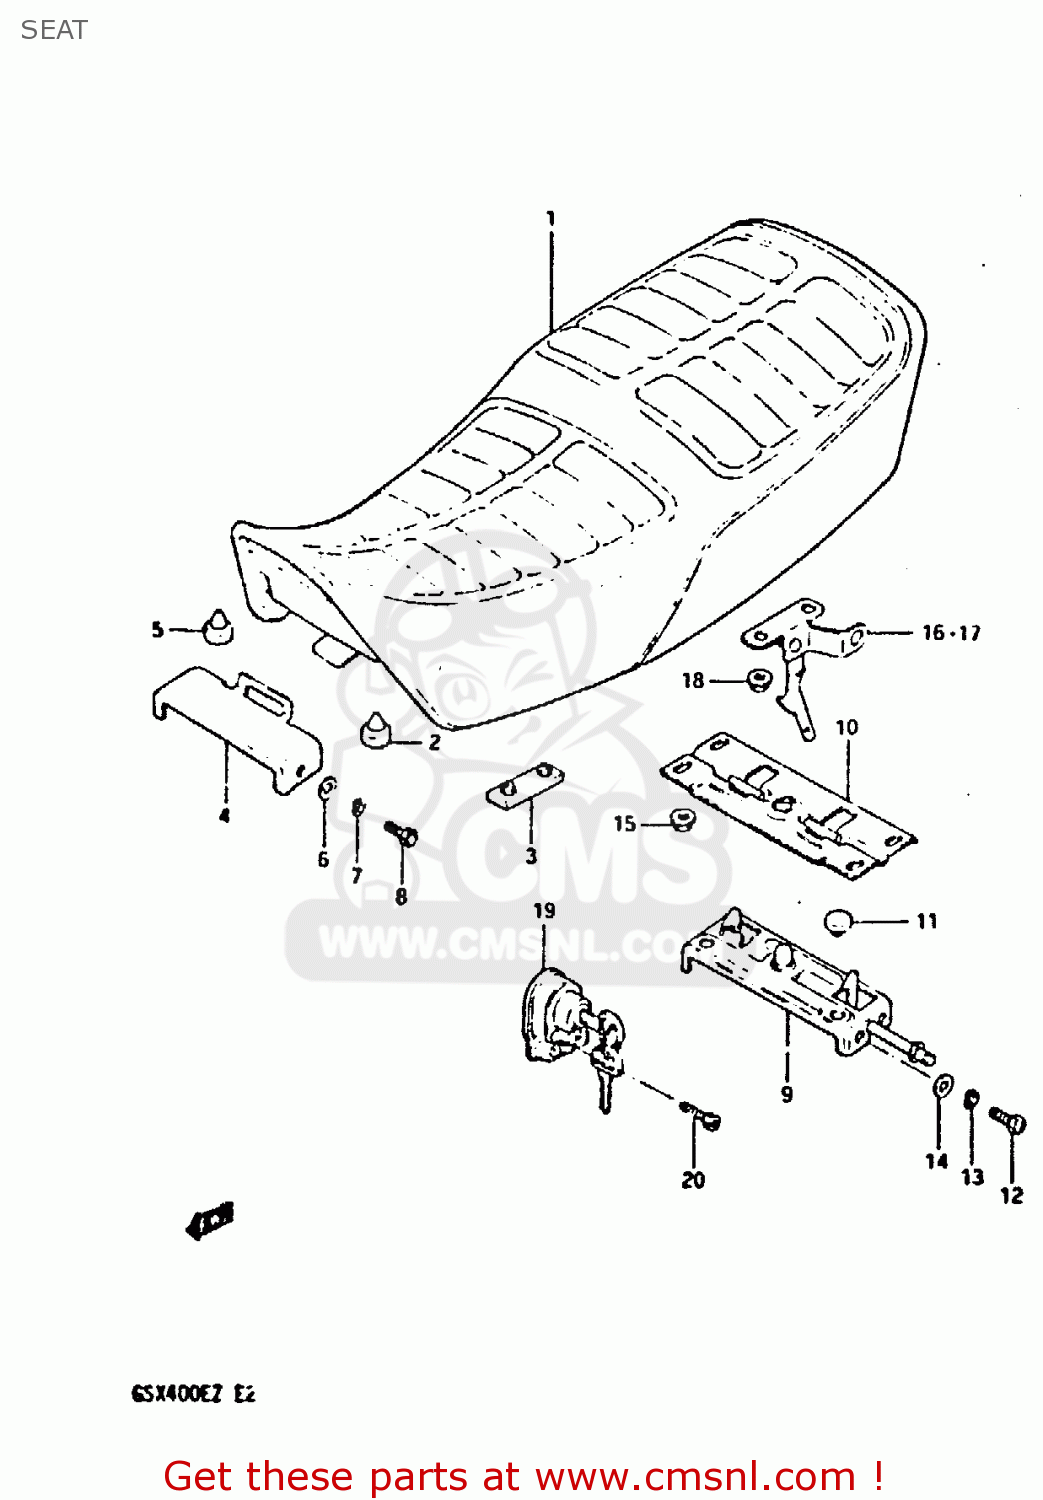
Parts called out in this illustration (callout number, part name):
1	SEAT ASSY (BLACK)
2	CUSHION
3	CUSHION
4	PLATE,SEAT LOCK,FRONT
5	CUSHION(11.5X22X20)
6	WASHER
7	LOCK WASHER
8	BOLT
9	PLATE,CLAMP GUIDE
10	PLATE,SEAT CLAMP GUIDE
11	CUSHION
12	SCREW
13	LOCK WASHER
14	WASHER
15	NUT
16	LEVER,SEAT HOOK,RIGHT
17	LEVER,SEAT HOOK,LEFT
18	NUT
19	LOCK ASSY,HELMET
20	BOLT 5X25
